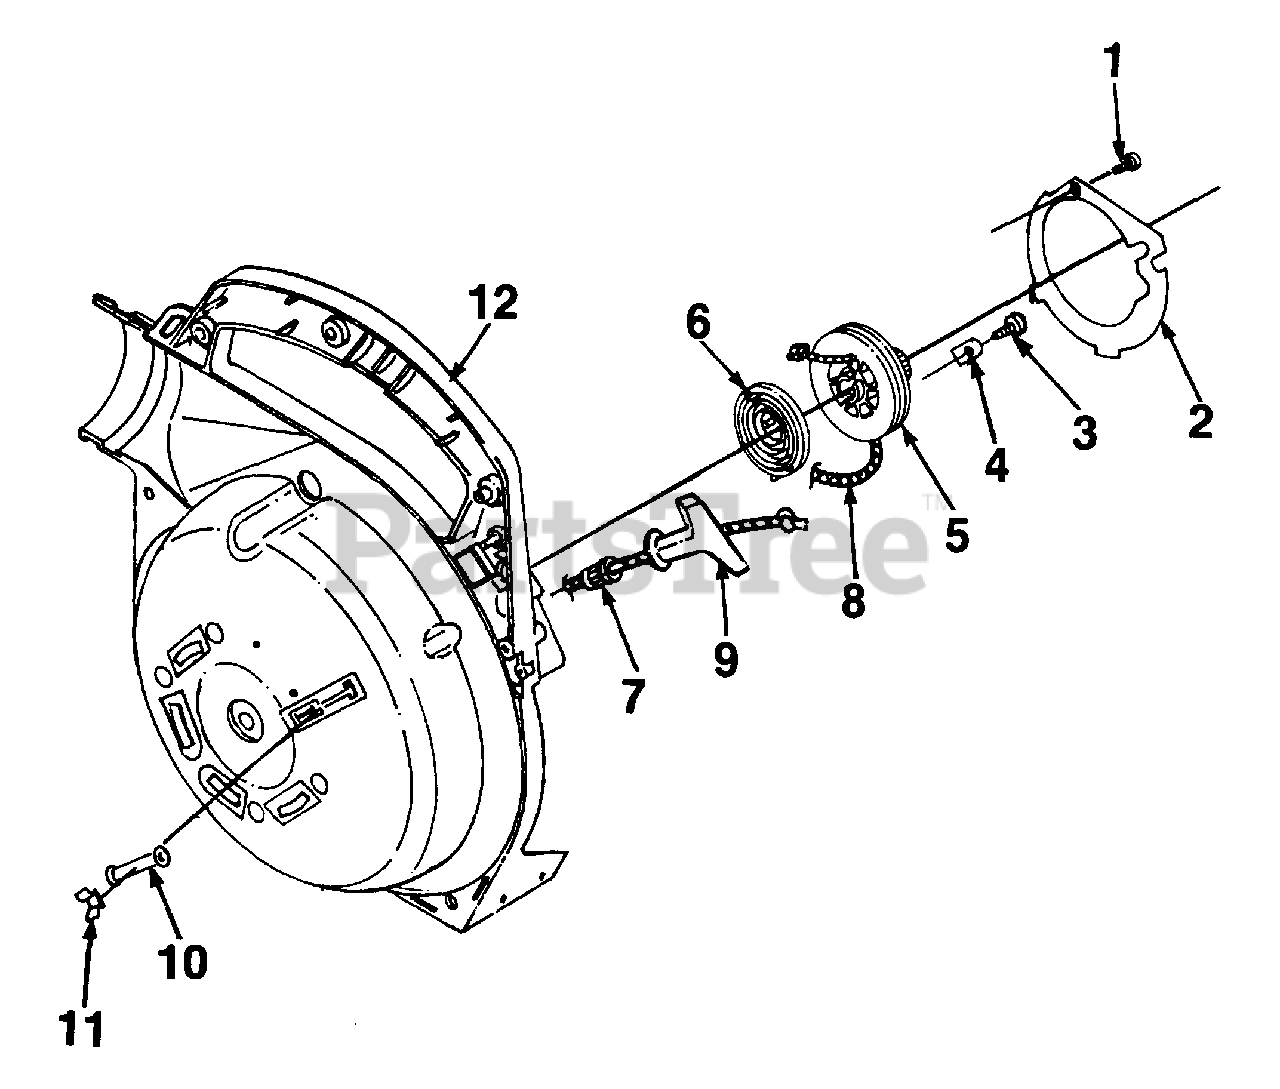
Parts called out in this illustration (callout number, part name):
1	SCREW - Thread Forming (#6-19 x 3/4 lg.)
2	PLATE - Rotor
3	SCREW - Thd forming 10 x 1/2
4	BRACKET - Retaining
5	PULLEY - Starter
6	SPRING & CONTAINER
7	BUSHING - Starter
8	ROPE - Starter 46"
9	GRIP - Starter rope
10	BUSHING - Starter rope
11	CLIP - Retainer
12	HOUSING - Volute (inner)
